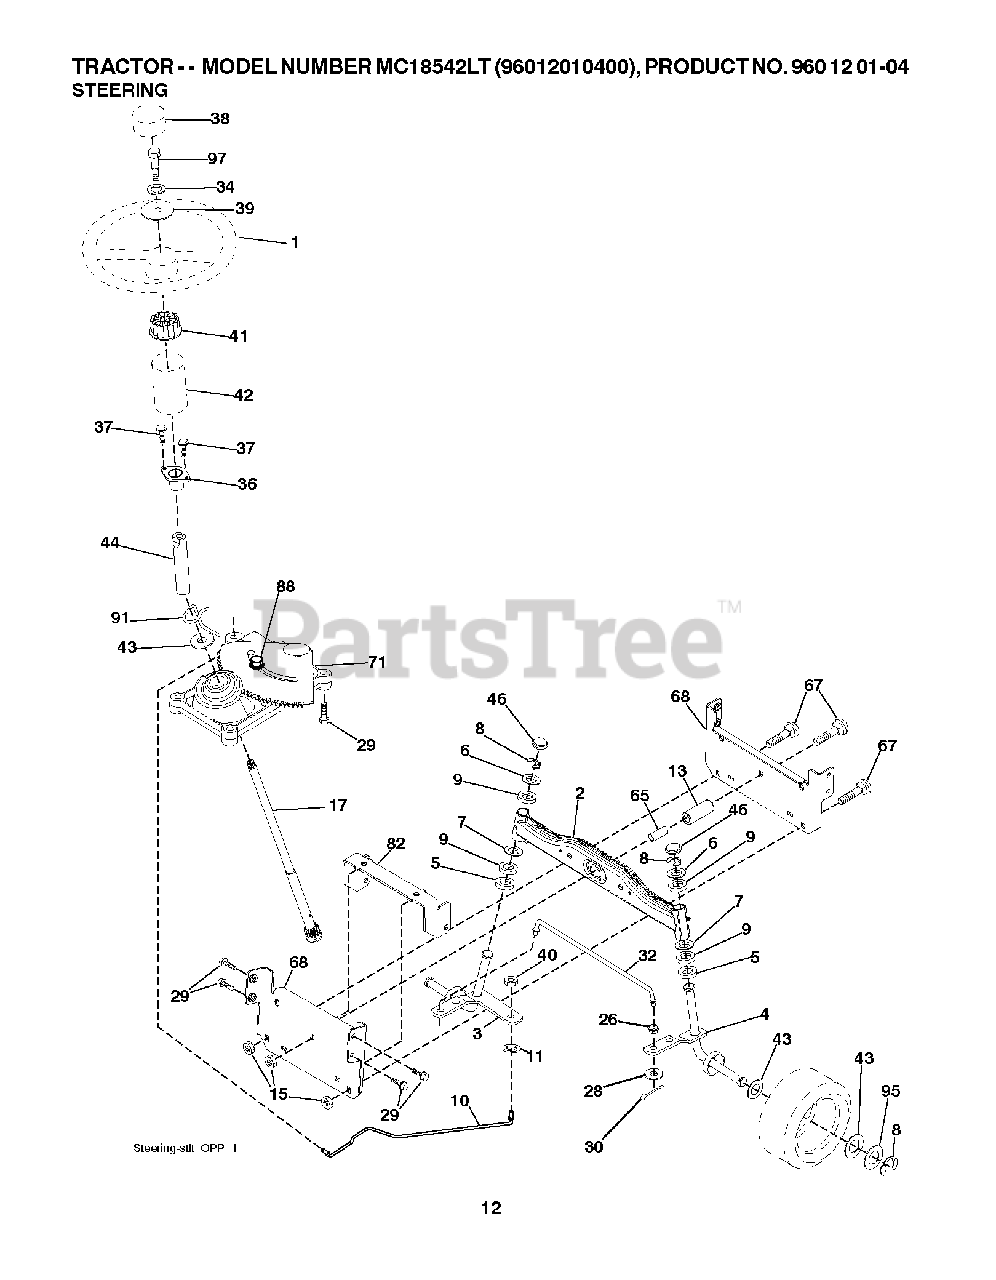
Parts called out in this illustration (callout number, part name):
1	WHEEL.STEERING.OPP.BLACK
2	AXLE HALF ASM-WELDED
3	SPINDLE.ASM.LH.15"TIRES
4	SPINDLE.ASM.RH.15"TIRES
8	RING CLIP
9	Steering Column Bearing
10	DRAGLINK.15".TIRES.2001
11	WASHER, LOCK 3/8
13	TUBE, PIVOT AXLE (2 2)
15	NUT LOCK FLG 3/8-16 UNC
26	BUSHING.DRAGLINK (2 2)
28	WASHER
29	SCREW, 3/8-16X3/4
30	COTTER PIN
32	ROD.TIE.WIRE.FORM
34	LOCKWASHER
37	SCREW.TT.#10-32X.5.3/8.FLANGE
38	CAP.WHEEL.STEER.OPP.BLK
39	WASHER.11/32
40	NUT CROWNLOCK 3/8-24
41	ADAPTER, WHEEL STNG..
42	BOOT.STEERING.SHAFT.BLACK
44	SHAFT.EXTEN.STRG.SPLINE
46	CAP.SPINDLE.BLACK
65	SPACER.BRACE.AXLE
67	BOLT CARRIAGE
68	BRACE.AXLE.15"TIRES
71	STEERING ASM
82	BRACKET.SUSP.CHASSIS.FRONT.15
88	BOLT, SHOULDER 7/16-20
91	CLIP.STEERING
95	WASHER.HARDENED
97	BOLT 5/16-18 X 4 W/PATCH
